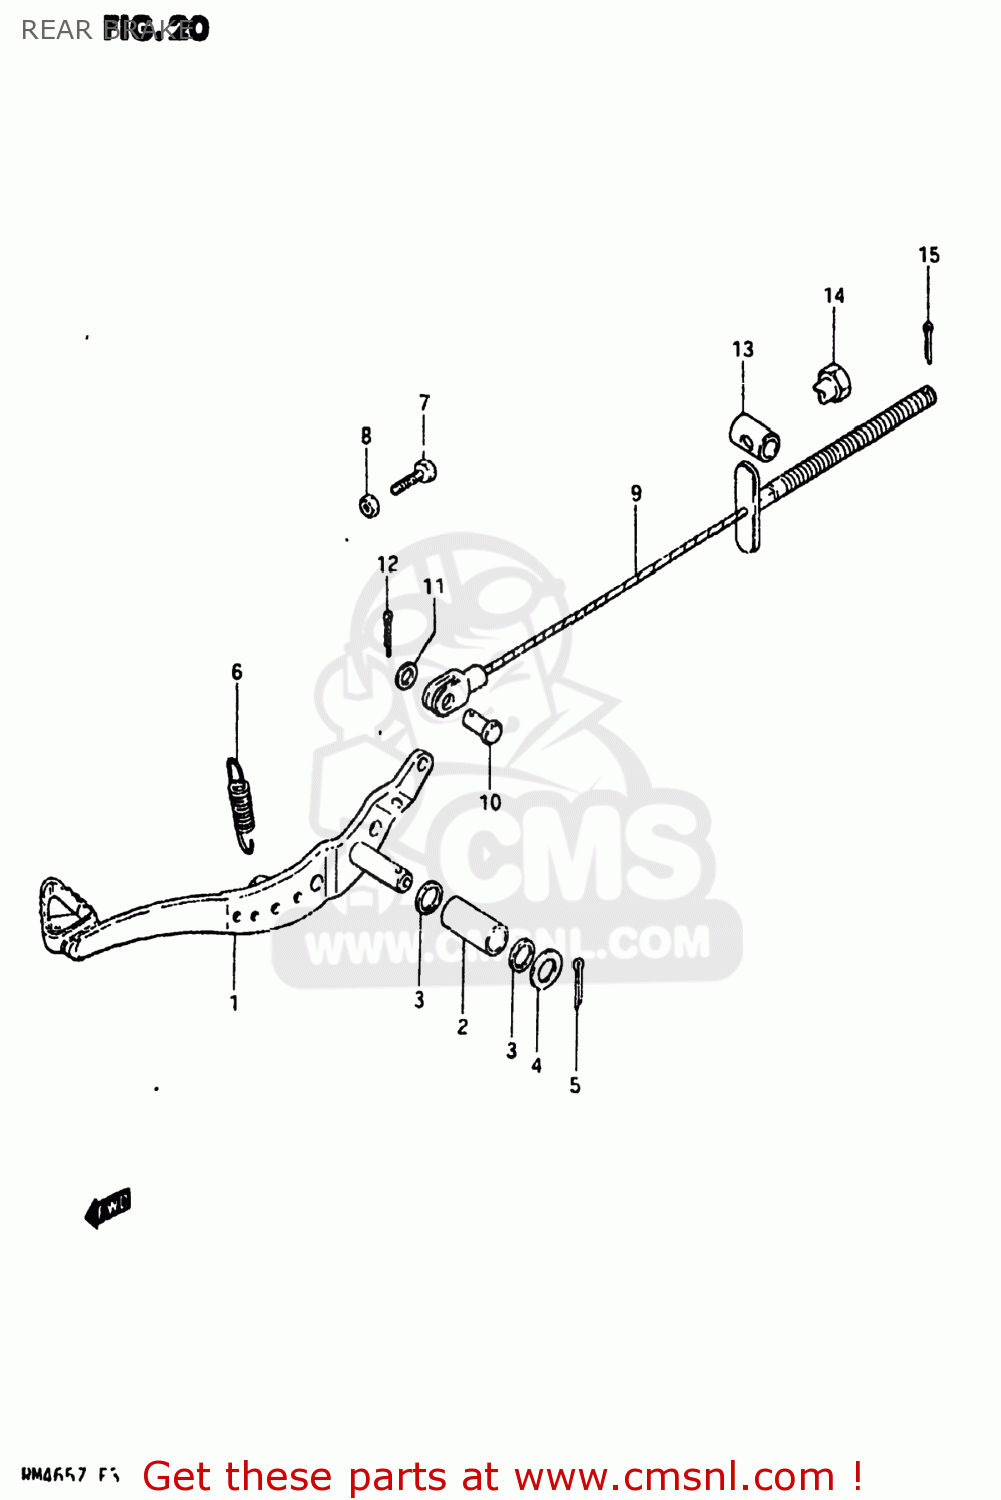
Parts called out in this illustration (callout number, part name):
1	PEDAL,BRAKE
2	BUSHING
3	O RING(D:2.2,ID:11.8)
4	WASHER
5	PIN 30X20
6	SPRING
7	BOLT(6X23)
8	NUT
9	CABLE,REAR BRAKE
10	PIN(L:17.5)
11	WASHER
12	PIN 20X20
13	PIN
14	NUT
15	PIN
